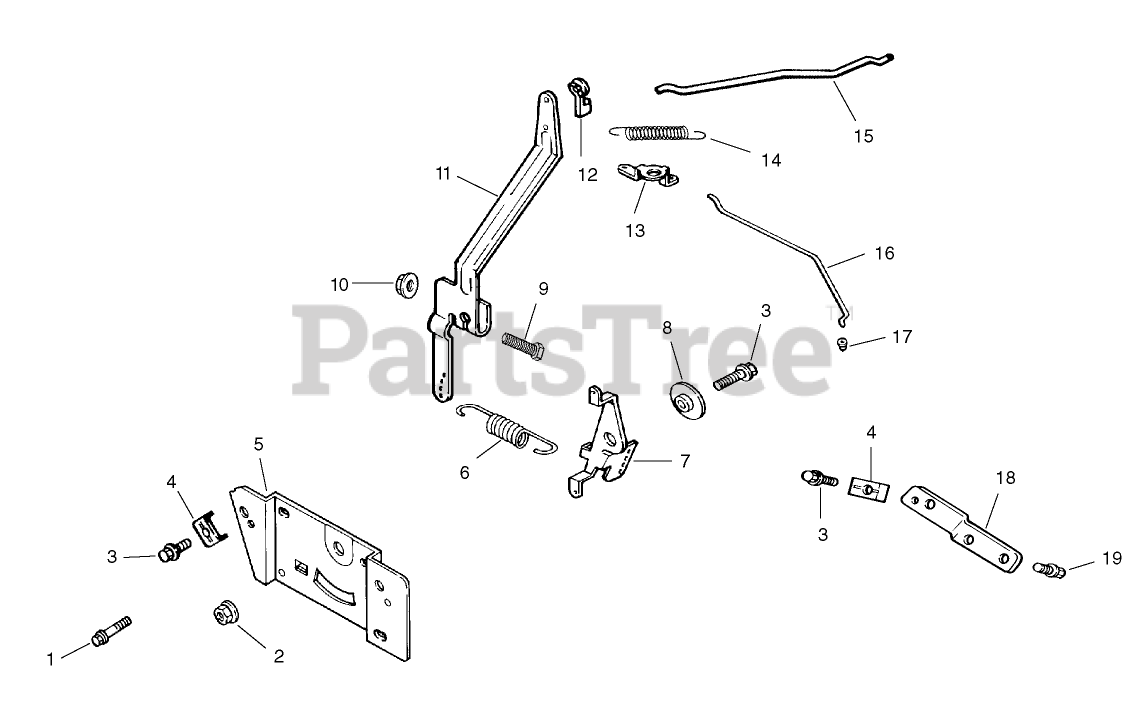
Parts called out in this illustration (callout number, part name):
1	Screw-Socket, 6 Lobed (Thread Forming, M6x1.0x20)
2	Nut-HF (M5x0.8)
3	SCREW-FLANGE, THREAD FORMING (M5X0.8X16)
4	CLAMP-CABLE
5	Plate-Control
6	Spring-Governor
7	Lever-Throttle, Inner
8	Spacer-Control ASM
9	Screw-Hex Flange, M6x1.0x25
10	NUT-FLANGE (M6X1.0)
11	Lever-Governor
12	BUSHING-RETAINING, LINKAGE
13	Lever-Choke, Upper
14	Spring-Linkage
15	Linkage-Throttle
16	Linkage-Choke, Upper
17	BUSHING-LINKAGE, THROTTLE
18	Bracket-Choke, Mount
19	SCREW-HHFTF (M5X.80X10)
